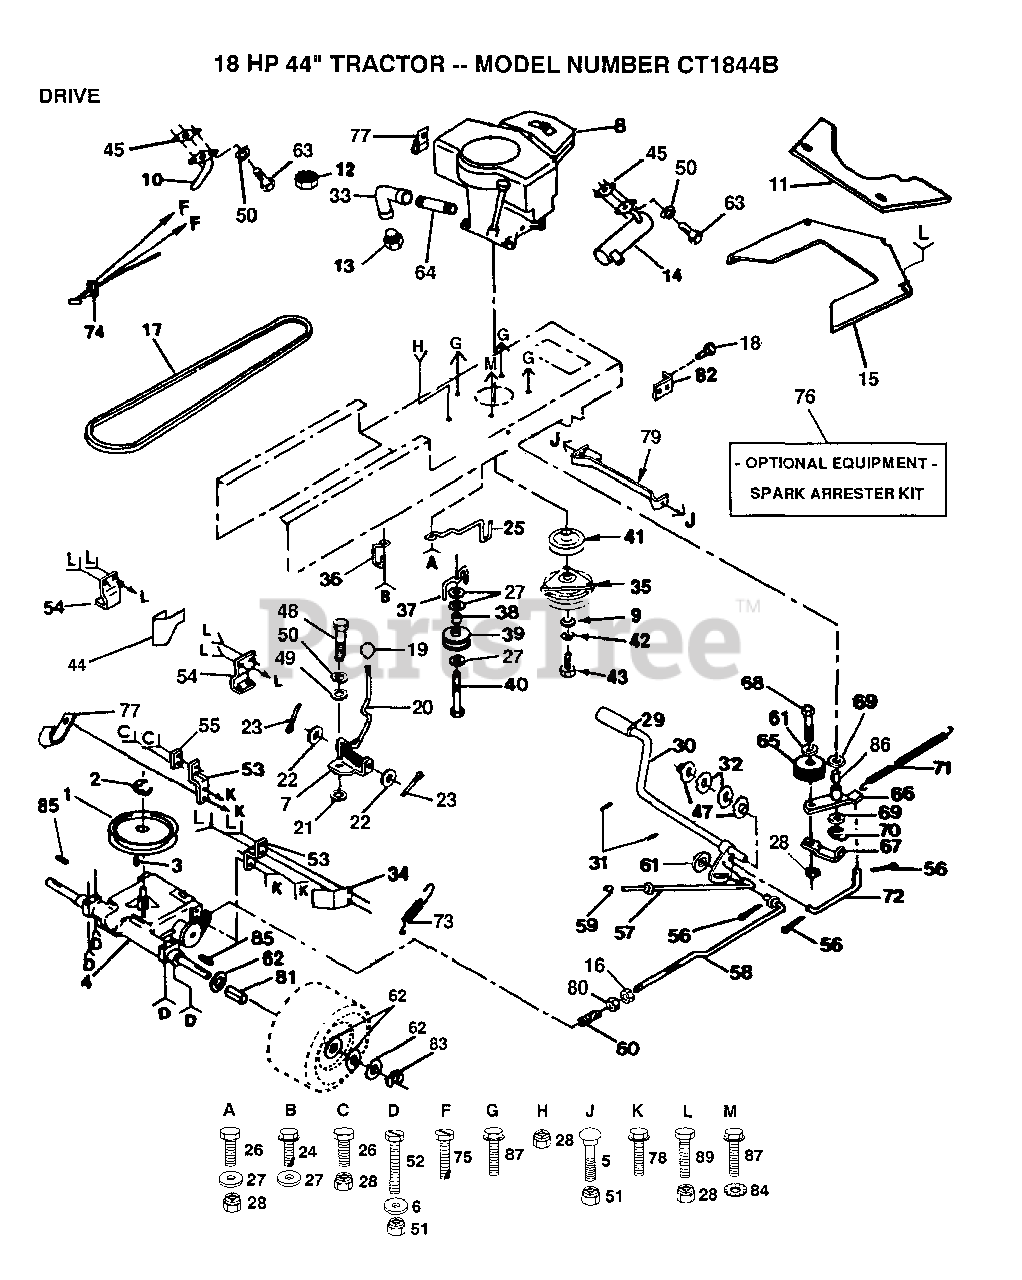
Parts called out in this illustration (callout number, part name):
1	PULLEY TRANSAXLE
2	RING
4	TRANSAXLE PEERLESS
5	BOLT
6	WASHER
7	PLATE SHIFT LT
9	WASHER
10	EXHAUST TUBE T
11	REAR BAFFLE T
12	NUT
15	SHIELD HEAT FRT
16	NUT
17	V BELT
18	SCREW
19	CONTROL KNOB LT
20	ROD SHIFTER T
21	WASH-SHFT PLT LT
22	WASHER
23	PIN COTTER 1/8
24	SCREW
25	KEEPER.BELT.ENG.L
26	BOLT
27	WASHER
29	PEDAL COVER T
32	WASHER LT
33	ELBOW
34	"KEEPER,BELT RH"
37	BELT KEEPER LT
38	SPACER T
39	PULLEY.IDLER.FLAT
40	BOLT
42	LOCKWASHER
44	"KEEPER,BELT LH"
46	BRKT TRANS RH
47	NYLON BEARING
49	WASHER LT
50	LOCKWASHER
52	BOLT HEX
53	STRAP TORQUE
54	BRACKET LT
55	PLATE-STRAP LT
56	COTTER PIN
57	ROD BRAKE PARK
58	ROD BRAKE
60	SPRING ROD LT
61	WASHER
62	WASHER
64	PIPE NIPPLE LT
66	ARM IDLER
67	RETAIN BELT
69	WASHER LT
70	KLIP RING
71	"SPRING, RETURN LT"
72	"LINK, CLUTCH T"
75	SCREW LT
76	SPARK ARREST KIT
77	CLIP T
78	SCREW
80	NUT
81	SPACER HYT
82	BRACKET LT
83	E RING HYT
84	LOCKWASHER
85	SQ KEY STD
86	"LY, BEARING"
87	SCREW LT
